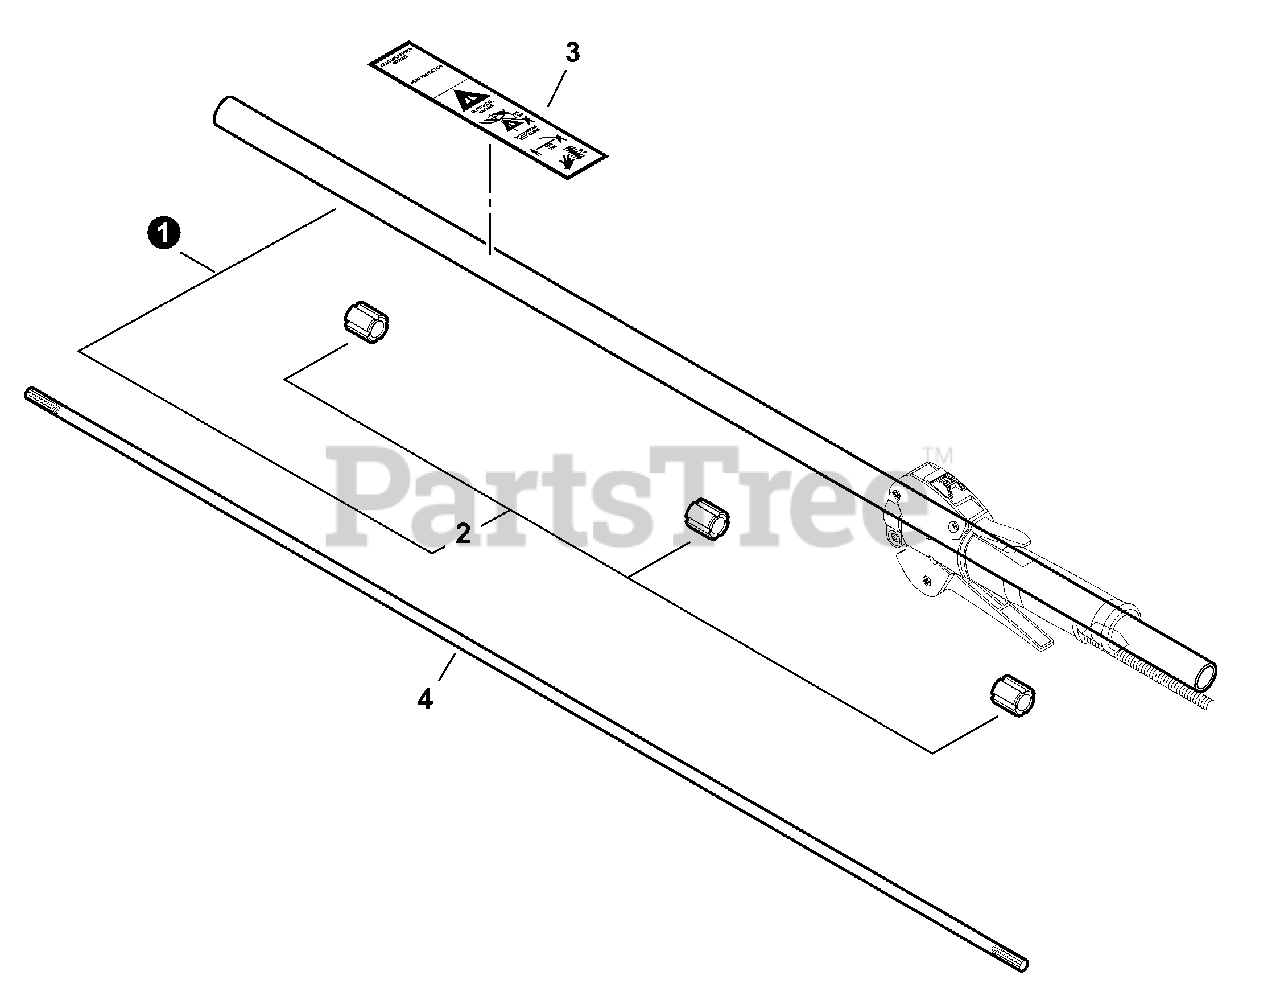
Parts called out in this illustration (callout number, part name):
1	MAIN PIPE ASSY
2	BUSHING
3	LABEL, CAUTION
4	MAINSHAFT 6×790 MM
